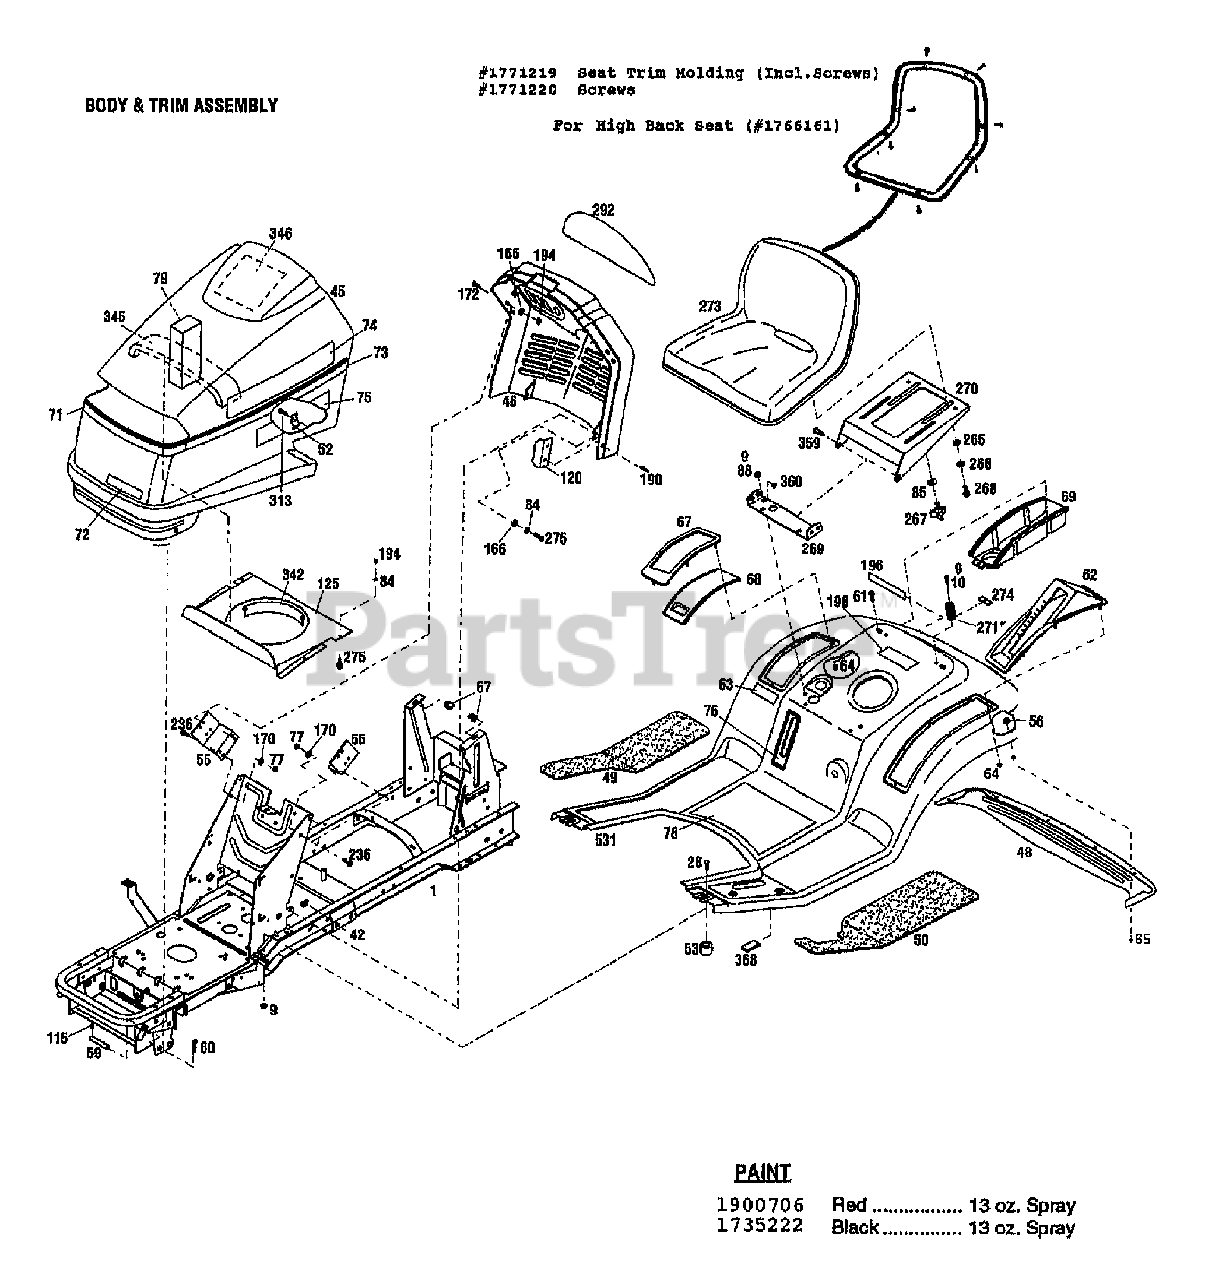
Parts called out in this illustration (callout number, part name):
9	NUT-HFLK 5/16-18 ZP
10	SCR-HHC 5/16-18X.75 GR 5 ZP
26	SCR-CARR 5/16-18X1.0 G2 ZP
42	NUT-SPEED
45	HOOD-TRACTOR
46	CONSOLE
48	TRIM-FENDER REAR
49	PAD-FOOT RH
50	PAD-FOOT LH
52	LATCH
53	SPACER-TUBULAR
55	BRKT-MOUNTING
56	NUT-HF/LK 1/4-20 ZP
59	PIN-PIVOT HOOD
60	PIN-HITCH .125X2.56 ZP
61	SCR-LOCK
63	DECAL-AMERICAN LEGEND-LRG
64	NUT-SELF THRD 1/4
65	SCR-HH 1/4-20X.625
67	TOP-STORAGE COVER
68	COVER-CONTAINER
69	CONTAINER-STORAGE
71	DECAL-STRIPE HOOD FRONT
72	DECAL-LOGO
73	DECAL-STRIPE SIDE
74	DECAL-LOGO TROY-BILT
75	DECAL-MODEL 13039 {13039}
75	DECAL-MODEL 13040 {13040}
76	DECAL-FUEL LEVEL
77	NUT-HEX 5/16-18 ZP
78	DECAL-OPER INST
79	BLOCK-SEALING
84	WASHER-LK .25 ZP
85	WASHER-FLAT 3/8 SAE
88	SCR-CARR 5/16-18X.62 G2 ZP
115	PIN-ROLL .188X1.0
120	BRKT-HOOD ALIGN
125	SHIELD-HEAT UPPER
166	WASHER-FLAT 1.25X.28X.062 ZP
170	WASHER-LK .312 ZP
190	RIVET-POP
194	NUT-HEX 1/4-20 ZP
196	DECAL-LOGO FENDER
198	DECAL-FUEL
236	SCR-HFLK 5/16-18X.75 ZP
266	WASHER-BOW .74X.52X.01
268	SCR-SHLDR 3/8-16X.25 G5ZP
269	BRKT-SUPPORT SEAT
270	SUPPORT-SEAT
271	SPRING-COMPRESSION
273	KIT-SEAT (TRACTOR)
274	BRKT-SPRING HOLD DOWN
275	SCR-HH 1/4-20X.625 G5 ZP
292	LENS-INSTRMTS WARN LIGHTS {13040}
292	LENS-INSTRMTS WARN LIGHTS {13039}
342	GASKET-HEAT SHIELD
345	STRIP-SEALING
346	DECAL-SERVICE
359	SCR-HH 3/8-16X.88 G5 ZP
360	NUT-H/LK 3/8-16
